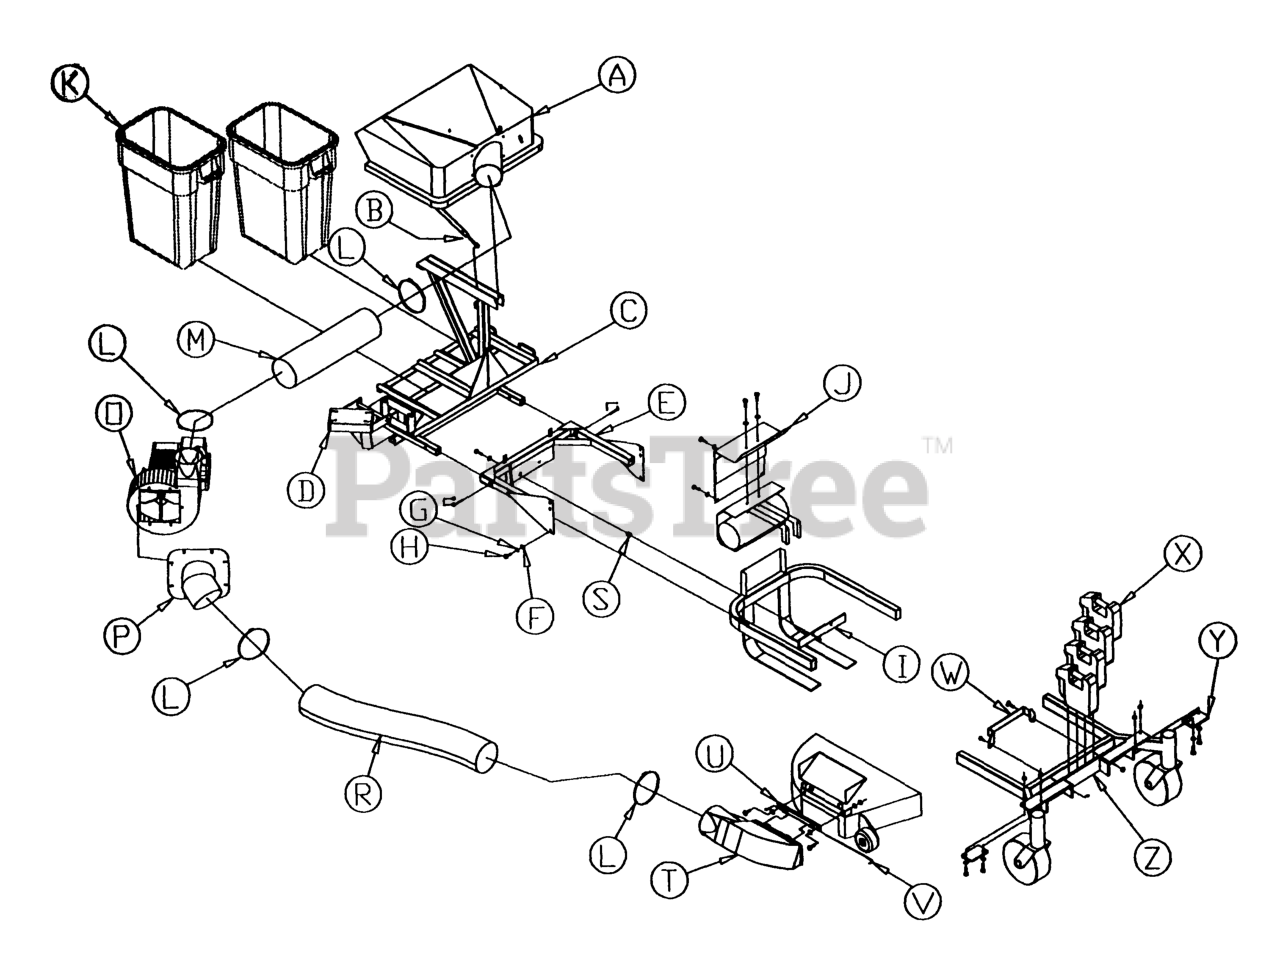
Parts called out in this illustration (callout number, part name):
O	Vacuum Assembly
A	Top Assembly
B	Gas Spring
C	Frame, Lazer Vac
K	Container, 30 Gallon, Green
M	Hose, 7" X 36", Black
R	Hose, 7" X 54", Black
E	Hitch, Base Lazer Vac
D	Engine Mount
J	Muffler Shield
T	Boot, Exmark 52"/60", 7" Neck
H	Bolt, Hex 3/8"-16 X 1-1/4"
F	Washer, Flat 3/8"
G	Washer, Spring Disc 3/8"
U	Qr Boot Bracket, 80562 Boot
S	Spacer, Idler Bracket
L	Clamp, Hose 7"
V	Rod, Quick-Release Boot
I	Hitch Plate, Lazer Vac
Y	Front Weight Clamp Plate
W	Front Weight Hold-Down Bar
P	Inlet Cover
Z	Front Weight Bar
X	Front Weight
